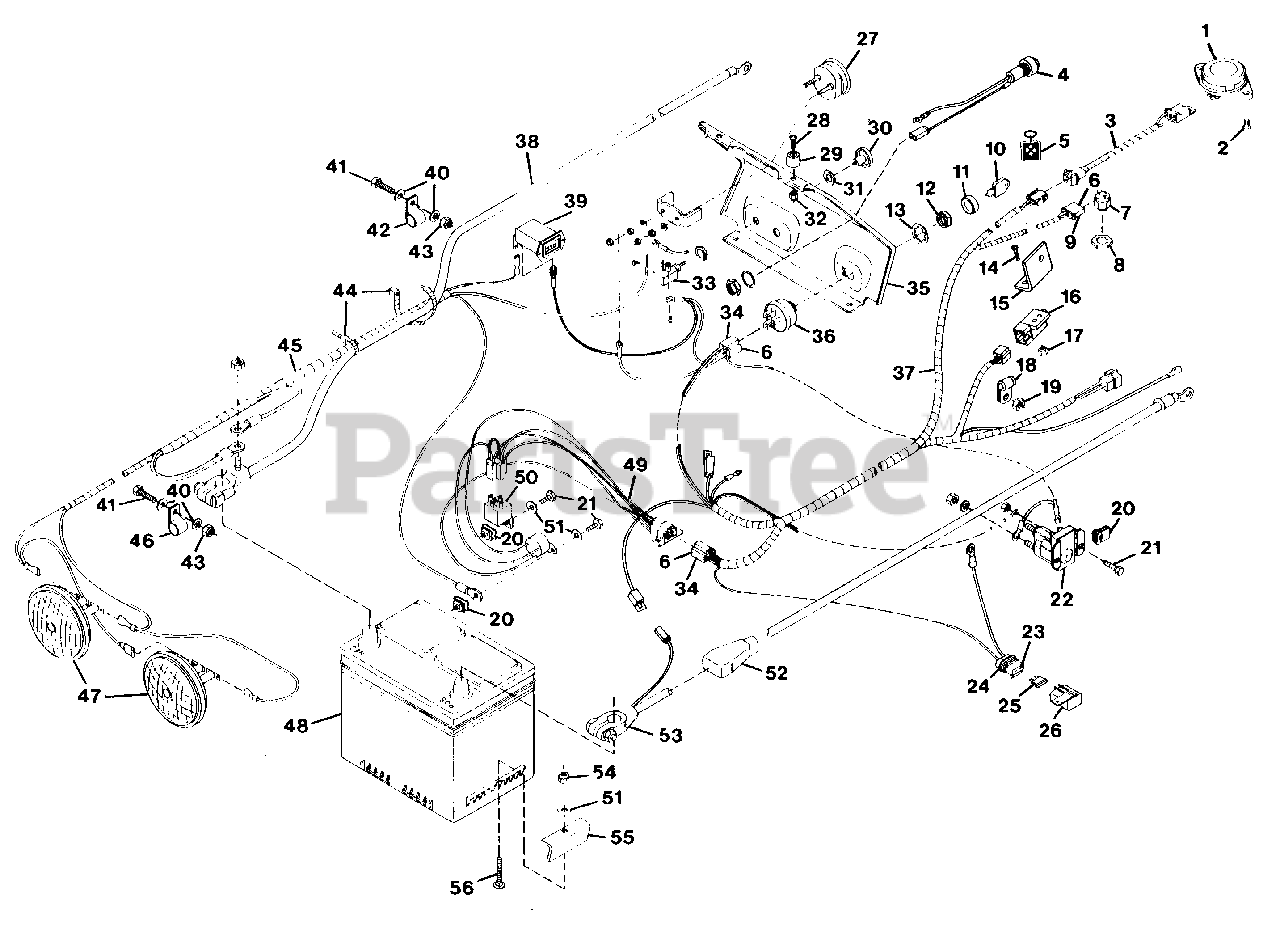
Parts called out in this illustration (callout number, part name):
1	SWITCH, SEAT
2	SCREW, MACHINE 1/4-20
3	HARNESS, WIRING SEAT SWITCH
4	LIGHT, INDICATOR
5	CHAIN, KEY
6	TERMINAL
7	SWITCH, INTERLOCK
8	NUT, STAMPED 9/16-18
9	CONNECTOR, 2-WIRE SWITCH
10	KEY, IGNITION SWITCH
11	BOOT, 9/16 SWITCH
12	NUT, JAM 9/16-24
13	WASHER, LOCK 9/16 INT. TOOTH
14	SCREW, MACHINE 10-24X.75 PHD
15	BRACKET, PTO SWITCH
16	SWITCH, INTERLOCK
17	NUT, LOCK 10-24
18	CLAMP
19	NUT, LOCK 3/8-16
20	NUT, SPEED 1/4-20
21	BOLT, HEX 1/4-20X.75
22	SWITCH, MAGNETIC
23	TERMINAL, 1J-16 GAUGE
24	CONNECTOR
25	FUSE, 25 AMP
26	COVER
27	GAUGE, AMMETER
28	SCREW, MACHINE 6-32X.625 PHD
29	BUMPER
30	KNOB, LIGHT SWITCH
31	NUT, SPECIAL LIGHT SWITCH
32	NUT, MACHINE LOCK 6-32
33	SWITCH, LIGHT
34	CONNECTOR
35	PANEL, SILK SCREEN
36	SWITCH, IGNITION
37	HARNESS, WIRING
38	CABLE, NEGATIVE BATTERY
39	HOURMETER
40	WASHER, FLAT .344X.688X.065
41	BOLT, HEX 5/16-18X1.00
42	CLAMP, NYLON
43	NUT, LOCK 5/16-18
44	TIE, CABLE
45	HARNESS, WIRING GROUND AND LIGHT
46	CLAMP, NYLON
47	HEADLIGHT
48	BATTERY, 12 VOLT
49	MODULE, TIME DELAY
50	RELAY
51	WASHER, FLAT .281X.625X.065
52	COVER, BATTERY TERMINAL
53	CABLE, STARTER
54	NUT, LOCK 1/4-20
55	CLAMP
56	BOLT, 1/4-20X2.00 RD HD SQ NK
NS	BOOT, BATTERY CABLE
